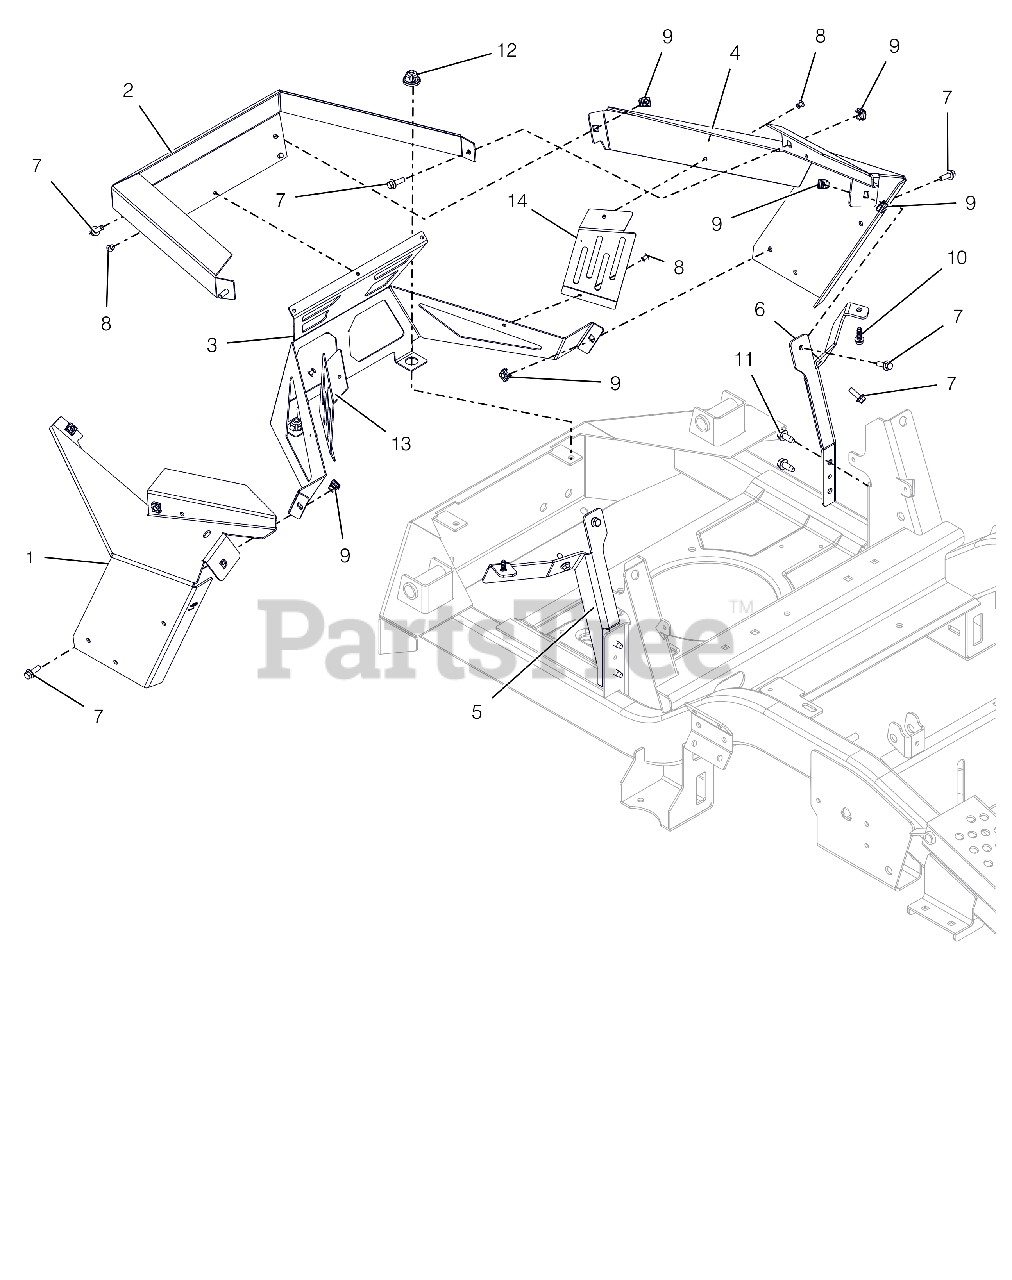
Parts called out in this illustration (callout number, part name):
1	PANEL,RIGHT REAR FENDER MOUNT
2	GUARD,ENGINE WRAP
3	GUARD,ENGINE
4	PANEL,LEFT REAR FENDER MOUNT
5	BRKT, RH FENDER MTG. APEX
6	BRKT, LH FENDER MTG -APEX
7	BLT,HEX-FLG .25-20X.75 G5 BFP
8	RIVET, .1875 AL/AL .126-.250
9	NUT RETNR .25-20
10	SCR-PLASTITE .25-10X.75, YWZC
11	@SCR-TAP .31-18X.75 HWH TR YWZ
12	GROMMET, 10MM BOLLHOFF
13	SHIELD,RH ENGINE GUARD VALVE
14	SHIELD,LH ENGINE GUARD VALVE
